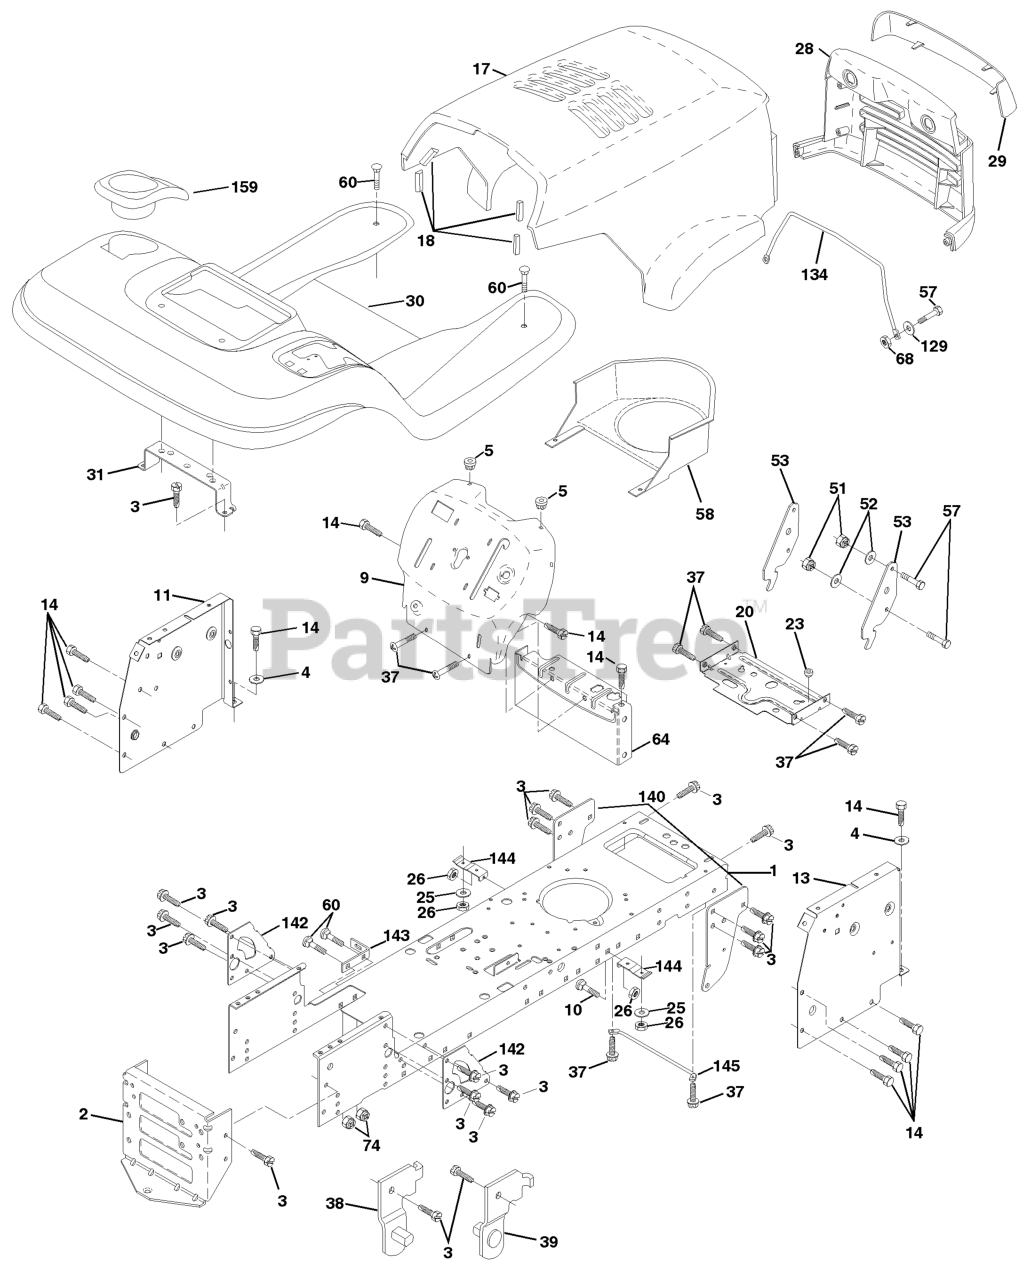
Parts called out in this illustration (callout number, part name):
1	CHASSIS
2	STRETCH DRAWBAR
3	SCREW
4	Washer 13/32 x 3/4 x 16 Ga.
5	BUMPER.RUBBER.HOOD
9	DASH PANEL
10	BOLT D
11	PANEL DASH LH
13	PANEL DASH RH
14	SCREW LT
17	HOOD
18	BUMPER HOOD T
20	PLATE MTG
23	BUSHING.SNAP.NYL.BLK.
25	WASHER
26	NUT
28	GRILL
29	LENS
30	FENDER
31	BRACKET.SUPPORT.FENDER
37	Screw Thdrol 6/16-18 x 1/2 TYT
38	BRACKET LH PIVOT
39	BRACKET RH PIVOT
51	LOCKNUT.NYLOC.1/4-20
52	WASHER
53	BRACKET PNT PICK OFF LT/PL
57	BOLT
58	AIR DUCT P/L/LT
60	Bolt Rdhd Sqnk 3/8-16unc x 3/4
64	DASH LOWER
68	NUT
129	WASHER
134	ROD SUPPORT HOOD LT/PL HUS.
140	BRACKET SUSPENSION FRONT
143	BRACKET, SWAY BAR
144	BRACKET FOOTREST
145	ROD PIVOT CHASSIS/HOOD
159	CUPHOLDER
